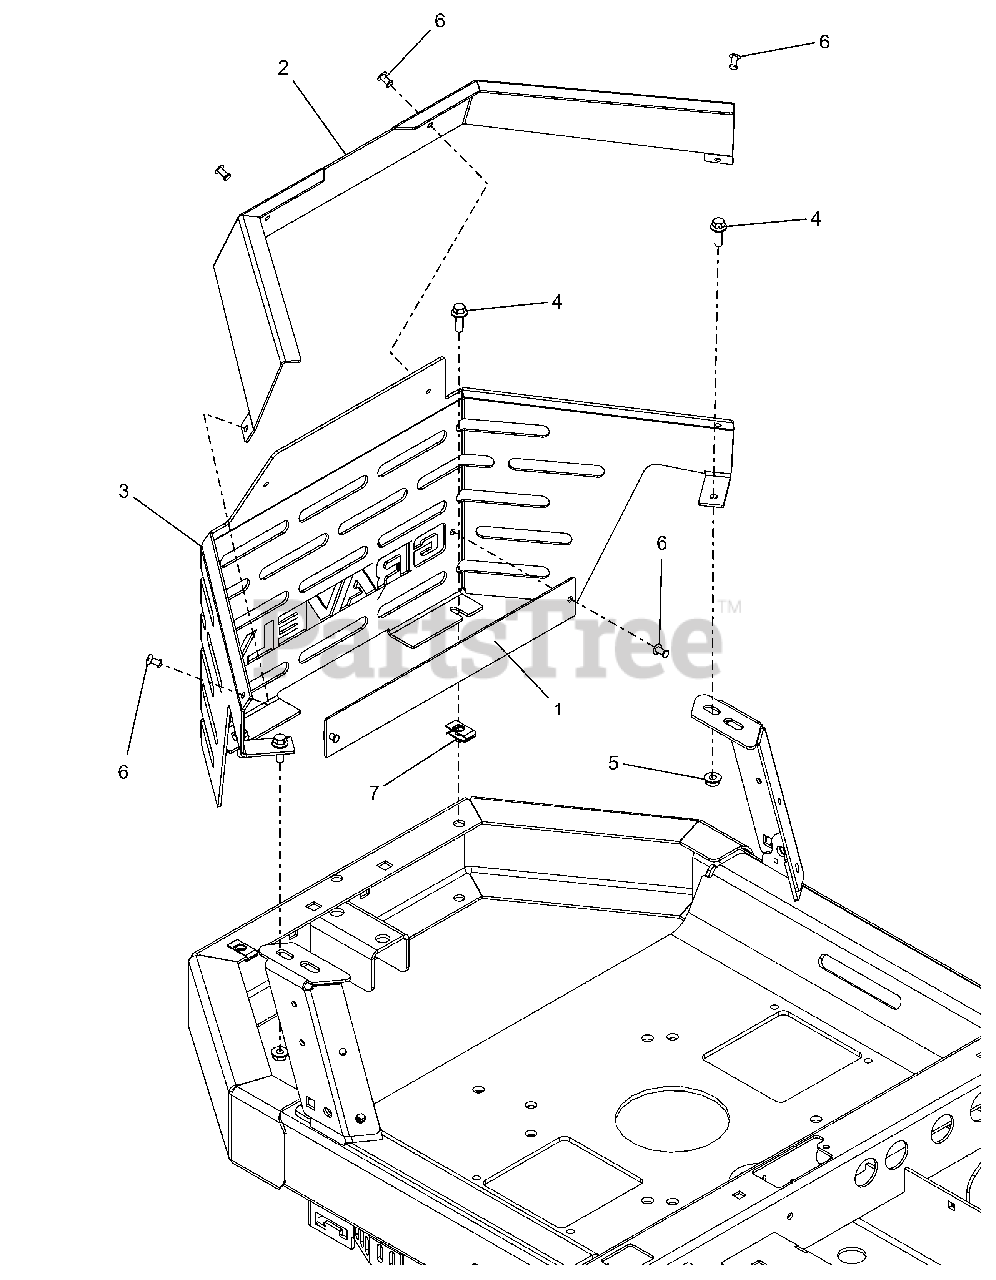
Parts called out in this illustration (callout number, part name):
1	PLATE, SHROUD BACKER
2	WLDMT, ENGINE SHROUD TRIM-XL
3	SHROUD, ENGINE - GRAVELY XL
4	BLT,HEX-FLG .25-20X.75 G5 BFP
5	NUT-LK-TOP-FLG .250-20 GF ZCC
6	RIVET, #66 STEEL POP PD BLACK
7	NUT-RTNR .25-20X.56
